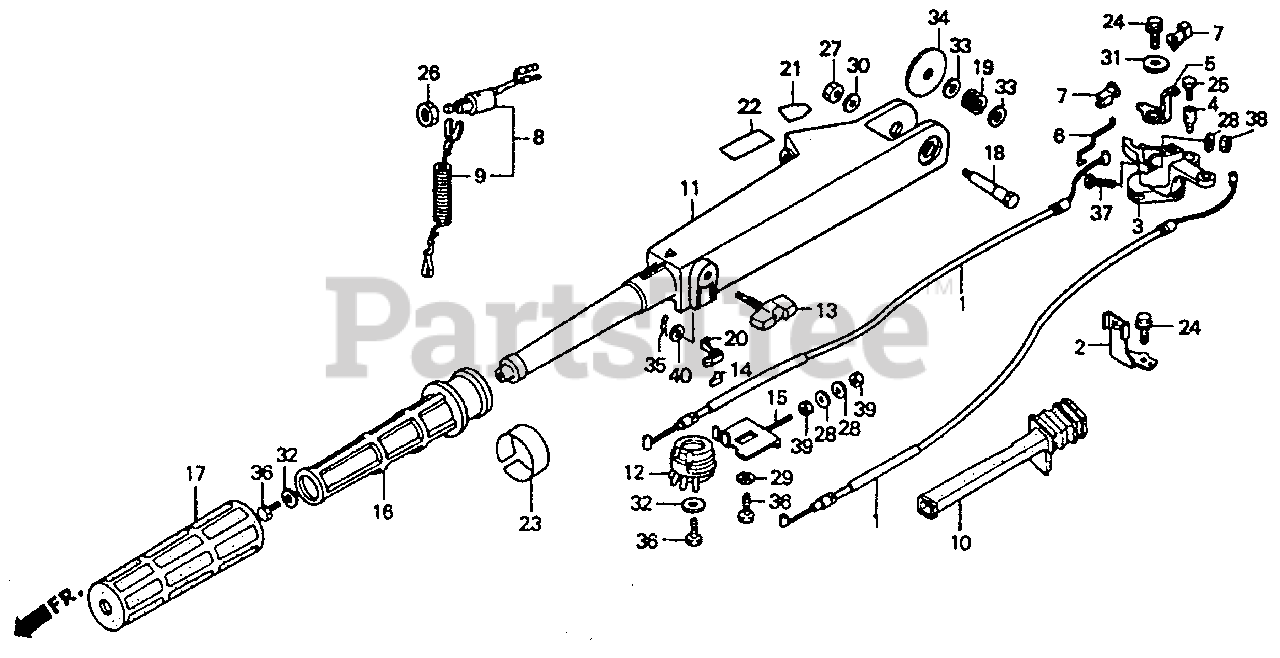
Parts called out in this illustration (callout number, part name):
1	CABLE, THROTTLE
2	CLAMP, THROTTLE CABLE
3	ARM, THROTTLE
4	HOLDER, THROTTLE ROD
5	ARM, CHOKE
6	ROD, CHOKE KNOB
7	BUSH, LINKAGE
8	SWITCH ASSY., EMERGENCY STOP
9	WIRE, EMERGENCY
10	GROMMET, OIL CASE (A)
11	HANDLEBAR *NH282MU* (OYSTER SILVER METALLIC-U)
12	REEL, CABLE
13	BOLT, FRICTION
14	BLOCK, THROTTLE FRICTION
15	PLATE, ADJUSTING
16	PIPE, GRIP
17	RUBBER, GRIP
18	SCREW, HANDLE PIVOT
19	SPRING, HANDLE PIVOT
20	SPRING, THROTTLE FRICTION
24	BOLT, FLANGE (6X12)
25	BOLT, RECESSED (5X8)
26	NUT, HEX. (16MM)
27	NUT, HEX. (8MM)
28	WASHER, PLAIN (5MM)
29	WASHER, PLAIN (6MM)
30	WASHER, PLAIN (8MM)
31	WASHER, PLAIN (6MM)
32	WASHER (6MM)
33	WASHER (10MM)
34	WASHER, HANDLEBAR
35	PIN, SPLIT (2.0)
36	BOLT, HEX. (6X12)
37	SCREW, PAN (5X40)
38	NUT, HEX. (5MM)
39	NUT, HEX. (5MM)
40	WASHER, FLAT (4MM)
